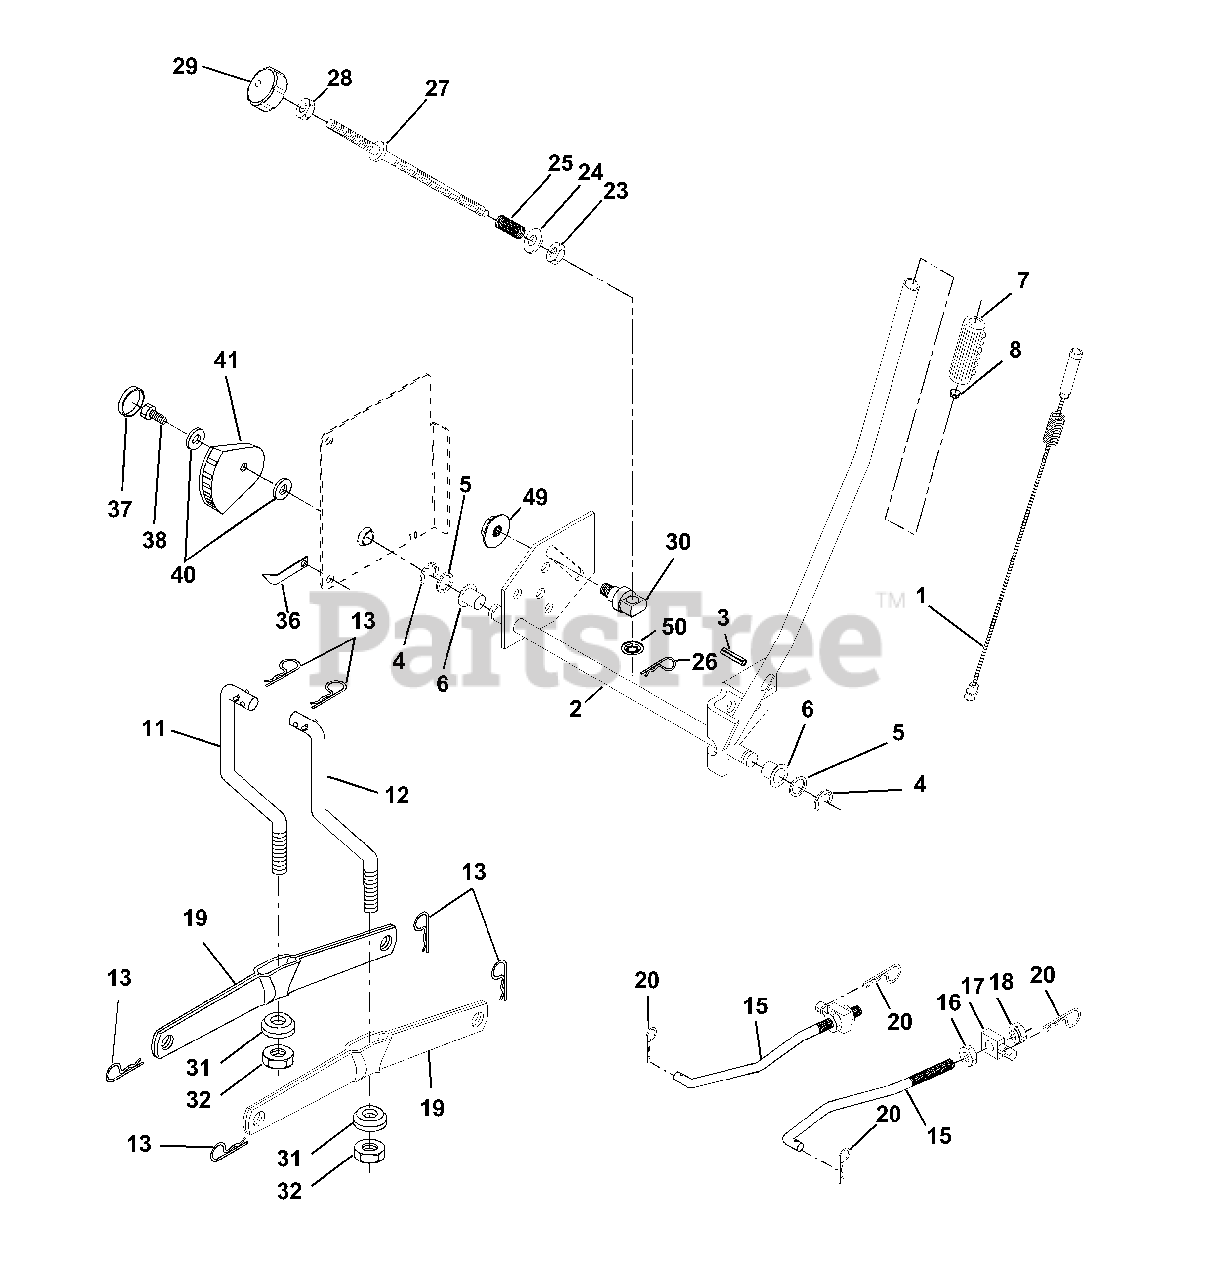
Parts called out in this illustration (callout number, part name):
1	Wire Asm Inner/Sprg W/plunger LT
2	Shaft Asm Lift RH w/Inf
3	Pin Groove 1 500 Zinc
4	E Ring #5133-62
5	Washer 21/32 X 1 X 21 Ga
6	Bearing Nylon Blk 629 Id
7	Grip Handle
8	Button Plunger Yellow
11	Link Lift LH Fixed Length
12	Link Lift RH Fixed Length
13	Retainer Spring
15	Link Front
16	Nut Jam Hex 1/2-13 Unc
17	Trunnion Blk Zinc
18	Nut Lock w/Wsh 1/2-13 Unc
19	Arm Suspension Rear
20	Retainer Spring
23	Nut Special
24	Washer 13/32 X 5/8 X 16 Ga
25	Spring 2-1/8"
26	Retainer Clip
27	Rod Adj Lift Zinc 7.49 Wrk Lg
28	Nut Hex Jam 3/8-16 Unc
29	Knob Inf 3/8-16 Unc Blk W/sym
30	Trunnion Infin Height
31	Bearing Pvt Lift
32	Nut Crownlock 3/8 - 24
36	Pointer Height Indicator
37	Plug Hole Blk 1.485/1.515 Dia.
38	Screw Thdrol 5/16-18 x 1
40	Washer 11/32 x 1-1/2 10 Ga.
41	Indicator Height STLT
49	Nut Hex Flange Lock
50	Nut PUsh Phos & Oil
